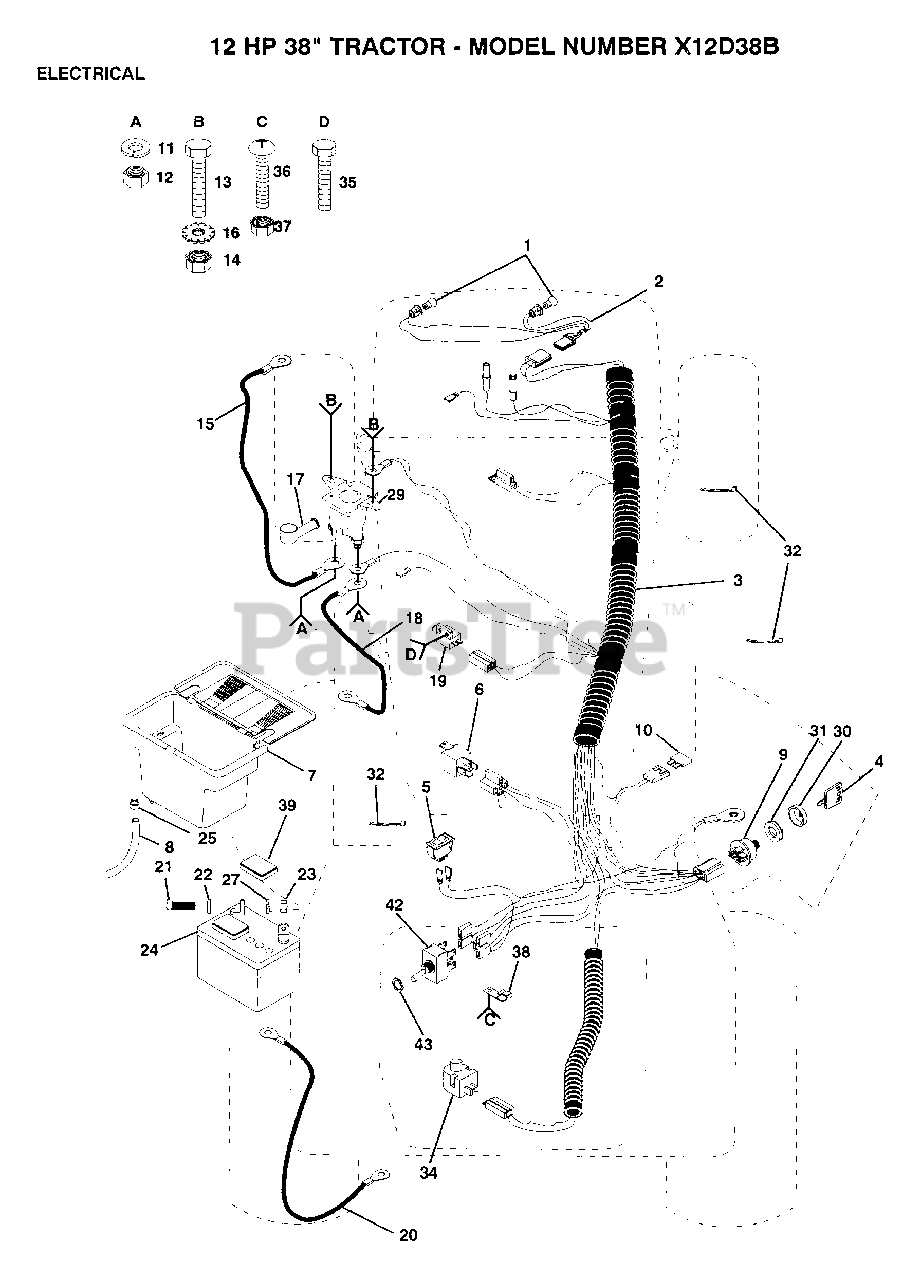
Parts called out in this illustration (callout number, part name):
2	HARNESS T
3	"HARNESS, IGNITION"
4	KEY
5	SWITCH LT
6	RELAY ASSY T
8	TUBE T
10	FUSE HYT
12	NUT
13	BOLT
14	NUT
15	"CABLE T, BATTERY"
19	SWITCH-INTER. GT
20	CABLE T
21	BOLT LT
22	WASHER
25	HOSE CLAMP T
27	LOCKWASHER
31	NUT IGNITION
32	WIRE TIE
34	SWITCH SEAT
35	SCREW
37	"NUT,KEPS"
39	"CAP,BATTERY "
43	HEX NUT T
